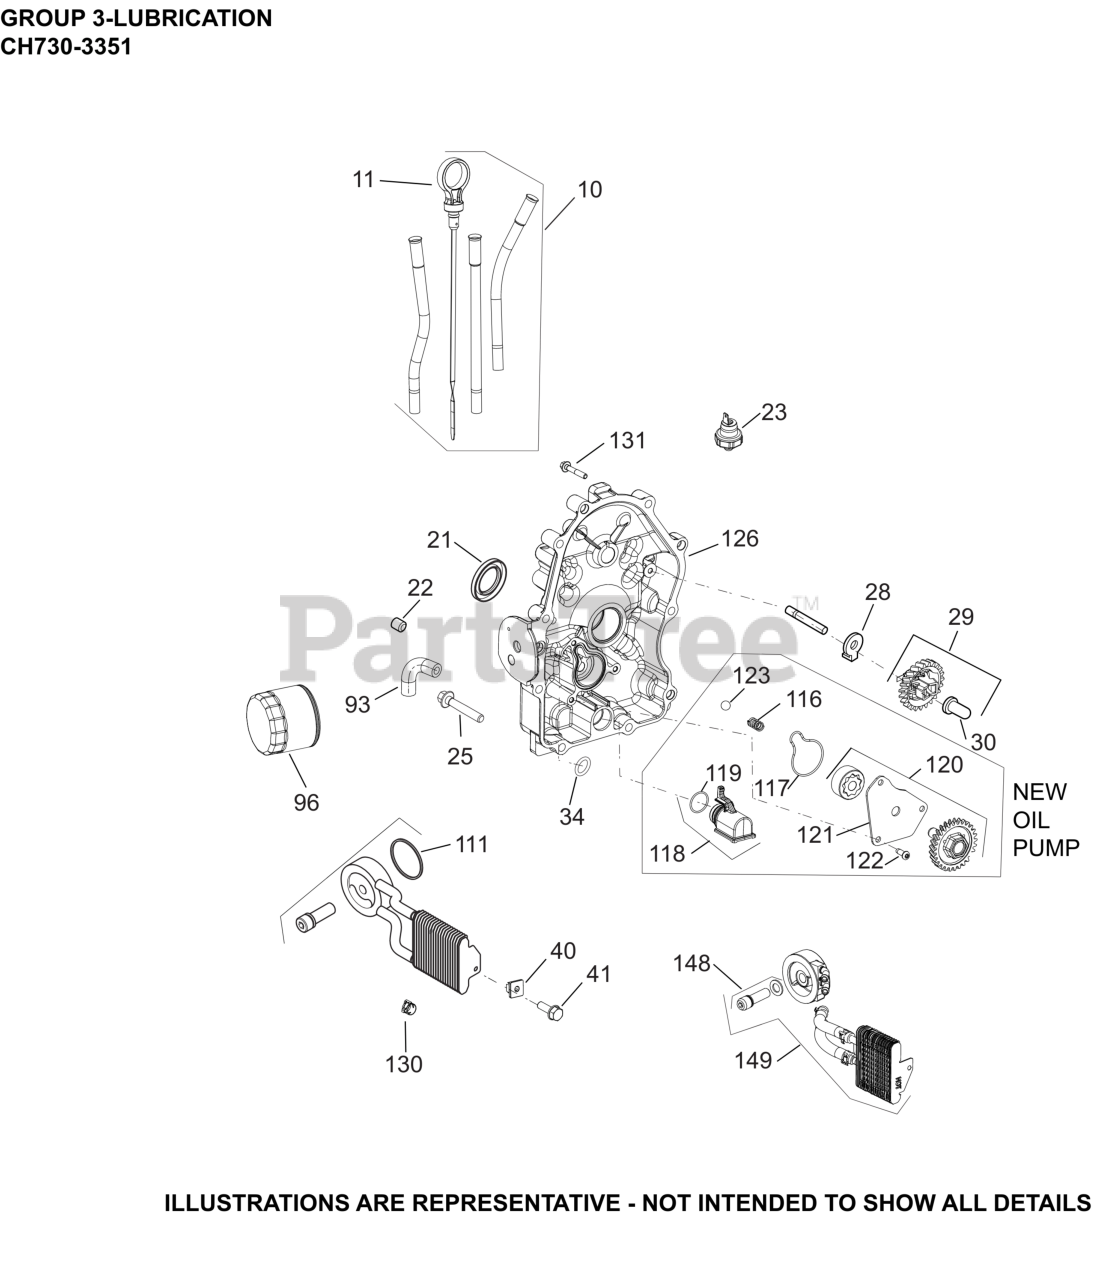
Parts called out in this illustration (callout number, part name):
10	KIT, DIPSTICK/DIPSTICK TUBES
22	PLUG, CTSK PIPE 1/8"
23	SENSOR, OIL PSI
25	SCREW, FLG M8X1.25X45
28	TAB, LOCKING
29	KIT, GOVERNOR GEAR W/PIN
30	PIN, GOVERNOR REGULATING
40	NUT, PLASTIC - BLACK
41	SCREW, HEX HEAD
93	KIT, HOSE 140MM
96	OIL FILTER
111	O-RING, OIL COOLER
116	SPRING, COMPRESSION
117	SEAL, OIL PUMP COVER
118	PICK-UP ASSEMBLY, OIL
119	O-RING, OIL PICK-UP
120	PUMP ASSEMBLY, OIL
121	COVER, OIL PUMP
122	SCREW, BUTTON HEAD
123	PRESSURE RELIEF BALL
126	KIT, CLOSURE PLATE ASSY
130	CLAMP, HOSE LOW PROFILE
131	SCREW, HEX FLANGE
148	KIT, OIL FILTER NIPPLE
149	KIT, OIL COOLER
NI	SHAFT, GOVERNOR GEAR
NI	WASHER, FLAT
